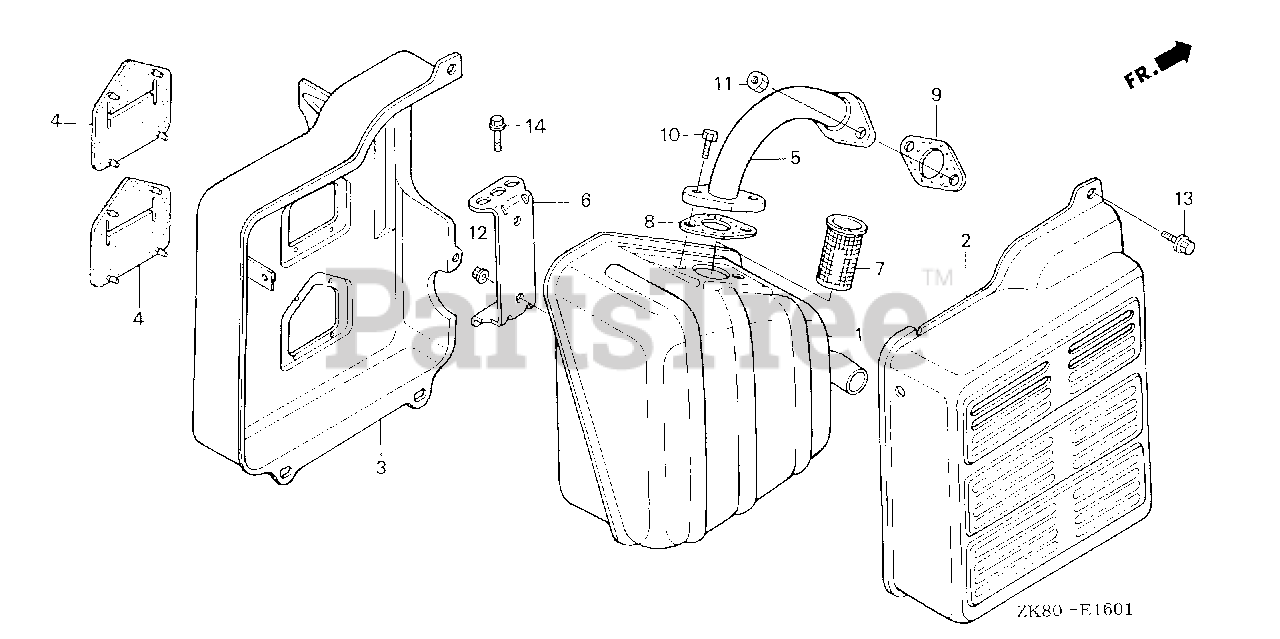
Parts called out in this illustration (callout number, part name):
1	MUFFLER
3	PROTECTOR, MUFFLER (INNER)
4	SEAL, MUFFLER PROTECTOR
6	STAY, MUFFLER
7	ARRESTER, SPARK
8	GASKET, MUFFLER
9	GASKET, MUFFLER
10	BOLT, HEX. (8X20)
11	NUT, HEX. (8MM)
12	NUT, FLANGE (6MM)
14	BOLT, FLANGE (8X20)
